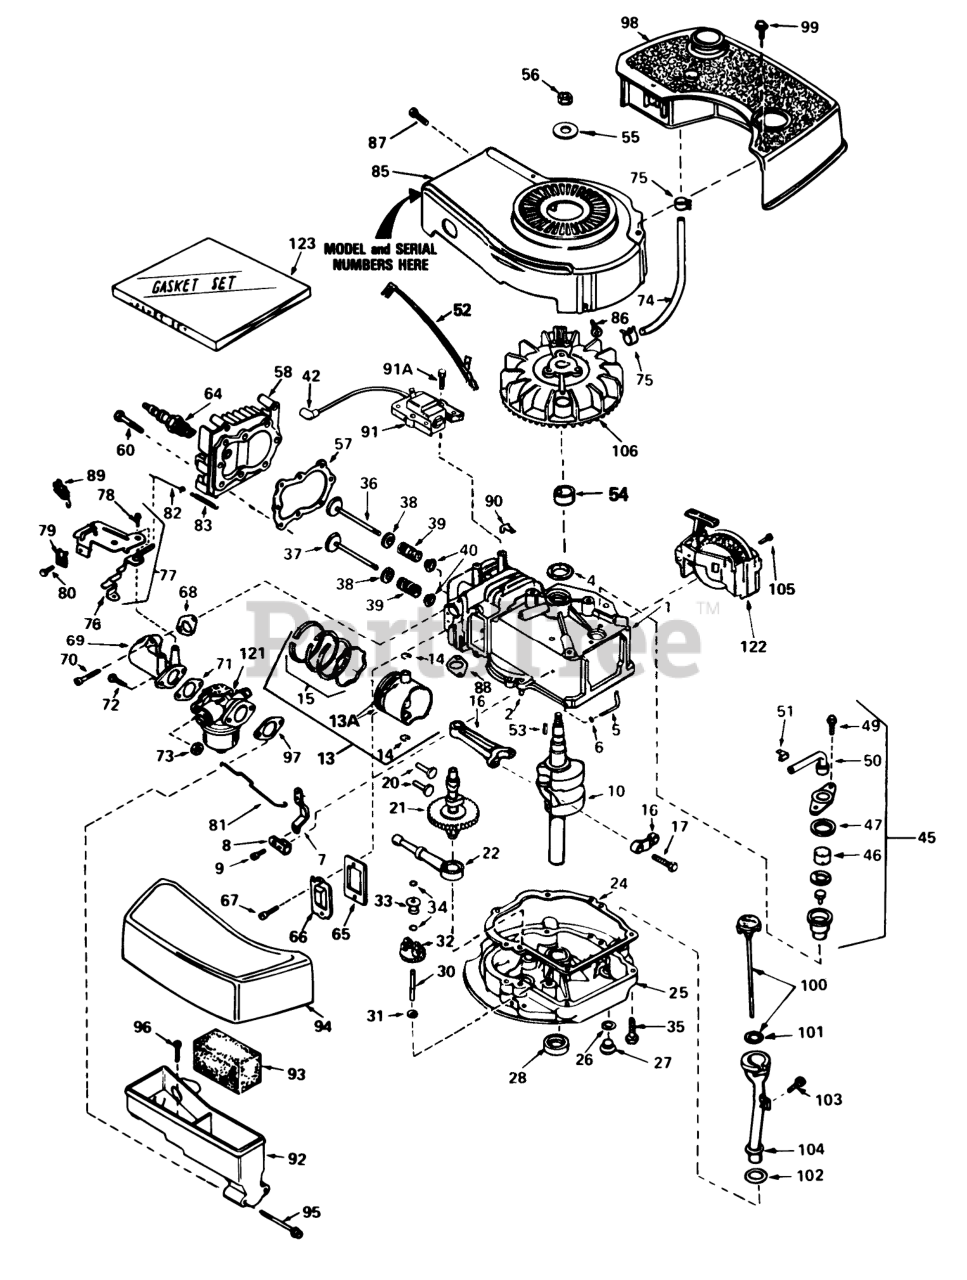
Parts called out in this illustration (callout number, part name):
1	Cylinder Assy.(Incl. Ref. #2 & 4)
2	Pin-Dowel
4	Seal-Oil
5	Rod, Governor (Incl. Ref. #6)
6	Washer-Flat
7	Governor Lever
8	Clamp-Lever, Governor
9	Screw
10	Crankshaft
13	Piston, Pin & Ring Assy. (Std.)(Incl. Ref. #13A,14 & 15)
13	Piston, Pin & Ring Assy.(.010 oversize)(Incl. Ref. #13A,14 & 15)
13	Piston, Pin & Ring Assy. (.020 oversize)(Incl. Ref.#13A,14& 15)
13A	Piston & Pin Assy. (Std.)(Incl. Ref. #14)
13A	Piston & Pin Assy. (.010 oversize)(Incl. Ref. #14)
13A	Piston & Pin Assy.(.020 oversize)(Incl. Ref. #14)
14	Ring-Retaining, Piston Pin
15	Ring Set (Std.)
15	Ring Set (.020" OS)
15	Ring Set (.010" OS)
16	Rod Assy., Connecting (Incl. Ref. #17)
17	Bolt-Rod, Connecting
20	Lifter-Valve
21	Camshaft(Mech.Comp. Release)
22	Oil Pump ASM
24	Gasket, Mounting Flange
25	Flange Assy., Mounting (Incl. Ref. #26 thru 30)
26	Gasket-Oil Drain
27	Plug Oil Drain
28	Seal Oil
30	Shaft-Governor
31	Washer-Flat
32	Gear Assy., Governor (Incl. Ref. #31)
33	Spool-Governor
34	Ring-Retaining
35	Screw (1/4-20 x 1-1/4)
36	Valve, Intake (Std.)(Incl. Ref. #40)
36	Valve, Intake (1/32" oversize)(Incl. Ref. #40)
37	Valve, Exhaust (Std.)(Incl. Ref . #40)
37	Valve, Exhaust (1/32" oversize)(Incl . Ref. #40)
38	Cap-Upper Valve Spring
39	Spring-Valve
40	Cap-Valve, Spring
42	Cover-Spark Plug
45	Breather Assy.(Incl . Ref. #46 thru 51)
46	Element-Breather
47	Gasket-Breather
49	Screw (10-24 x 9/16)
50	Tube, Breaker
51	Clip, Breather
52	Wire-Ground
53	Key-Flywheel
55	Washer-Belleville
56	Nut-Flywheel
57	63573 GIL 42 SNWTHW
58	Head-Cylinder
60	Screw (5/16-18x1-1/2)
64	Plug, Spark (J17LM or equiv.)
64	Plug, Spark (Champion RCJ-8)
65	Gasket-Breather
66	Cover-Valve
68	Gasket-Intake
69	Pipe, Intake (Incl. Ref. #68)
70	Screw (1/4-20 x 1)
71	Gasket-Carburetor
72	Screw (1/4-28 x 7/8)
73	Nut and Lock Washer (1/4-28)
74	Line-Fuel
75	Clamp-Line, Fuel
76	Lever Control
77	Control Assy., Speed (Incl. Ref.#76,78&89)
78	Screw, Hex Washer Hd Shoulder Self-Tap
79	Conduit
80	Screw (10-32 x 3/8)
81	Link-Throttle
82	Link Governor Spring
83	Spring Governor
85	Housing-Blower
86	Screw (1/4-20x19/32)
87	Screw (10-24 x 9/16)
88	Gasket Exhaust
89	Terminal
90	Clip-Wire
91	Lamination & Coil Assy.(Solid State)(Incl. Ref. #42)
91A	Screw
92	Body Air Cleaner
93	Filer, Air
94	Cove, Air Cleaner
95	Screw Fil Hd.
96	Screw, Hex Hd.
97	Gasket-Air Cleaner
98	Tank-Fuel
99	Screw (10-32 x 35/64)
100	Dipstick, Oil (Incl. Ref. #101)
103	Screw (10-32 x 1/2)
104	Tube-Oil Fill
105	Screw (1/2-20x5/8)
106	Flywheel
121	Carburetor (Incl. Ref. #71)
122	Starter-Sidemount
123	Gasket Set (Incl. Items Marked )
